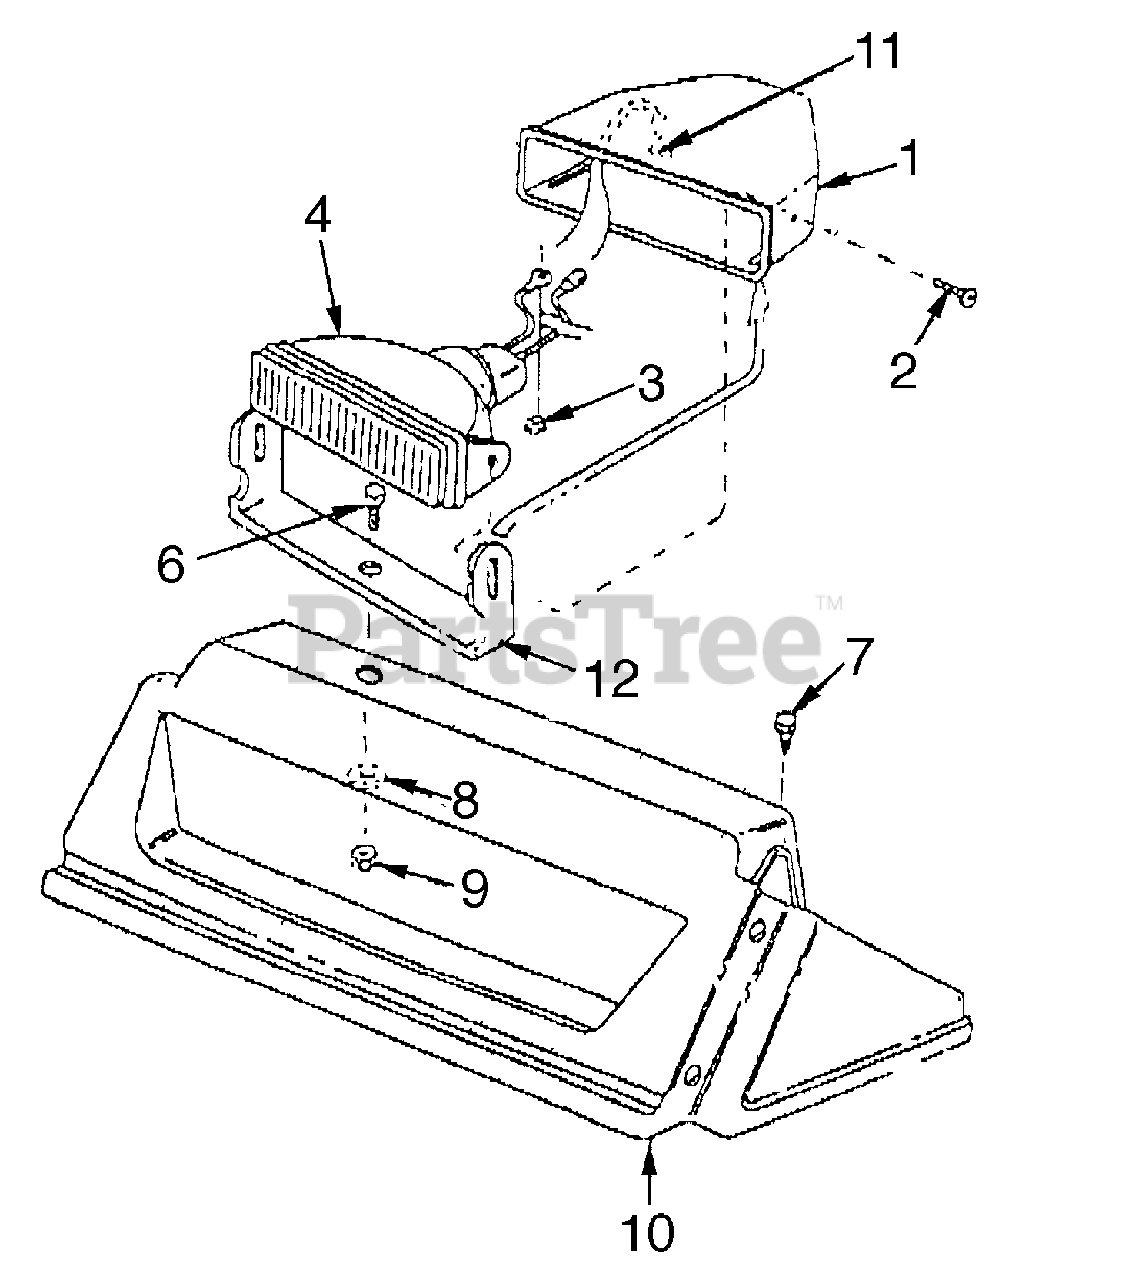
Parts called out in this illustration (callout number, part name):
1	Halogen Lamp Housing
2	Phillips Pan Head Screw M 4 x 16
3	Hex Sems Nut 1/4-20
4	Lamp/Lens Housing Ass'y
6	Carriage Bolt 5/16-18 x .75
7	Pan Head B-Tapp Screw #10
8	Fl-Wash .344 ID x .88 OD
9	Hex Ins L-Nut 5/16-18
10	Handle Panel
11	Grommet .38 ID x .50 OD x 12
12	Lamp Mounting Bracket
